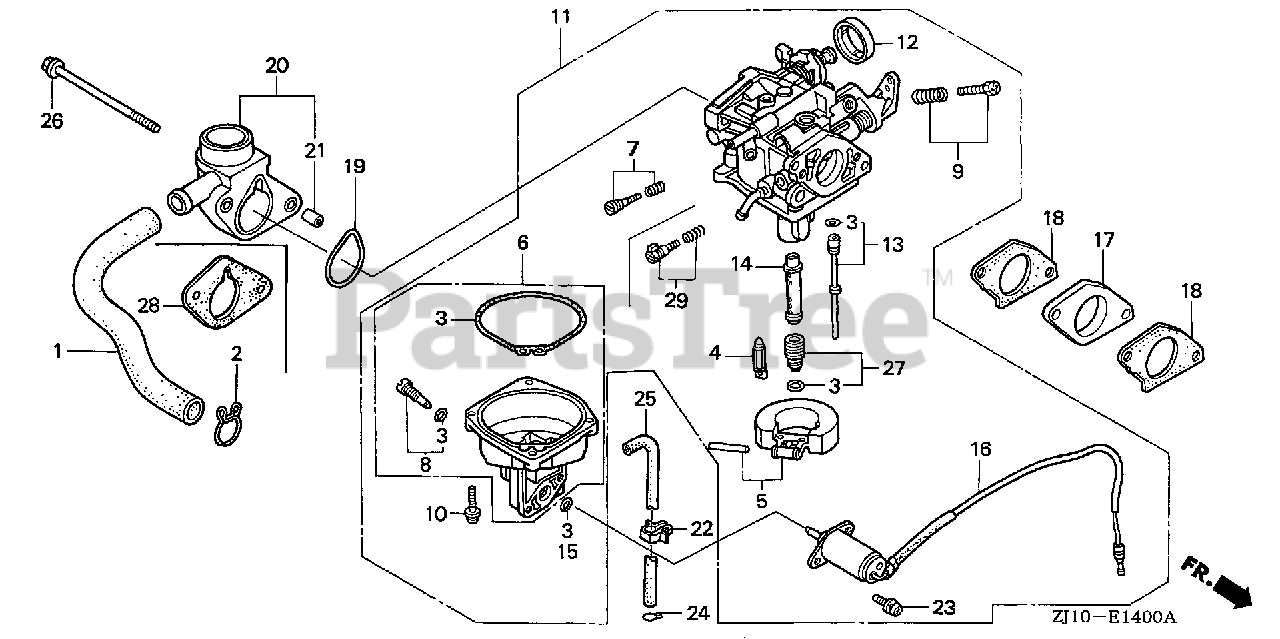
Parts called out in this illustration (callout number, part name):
1	TUBE, BREATHER
2	CLIP, BREATHER TUBE
3	GASKET SET
4	VALVE SET, FLOAT
6	CHAMBER SET, FLOAT
8	SCREW SET, DRAIN
9	SCREW SET (CARBURETOR NO.)
10	SCREW-WASHER
11	CARBURETOR ASSY. (BG22A C)
12	CAP, CHOKE DUST
13	JET SET (#45) (CARBURETOR NO.)
14	NOZZLE, MAIN
15	O-RING (5.8X1.9)
16	VALVE ASSY., SOLENOID
17	INSULATOR, CARBURETOR
18	GASKET, CARBURETOR
19	GASKET, AIR CLEANER
20	ELBOW, AIR CLEANER
21	COLLAR, DISTANCE
22	CLIP B, CABLE (9MM BLACK)
23	SCREW-WASHER (5X12)
24	CLIP, TUBE (B8)
25	BULK HOSE, VACUUM (4.5X1000) (4.5X460)
26	BOLT, FLANGE (6X105)
27	JET SET, MAIN (#90)
27	JET SET, MAIN (#92)
27	JET SET, MAIN (#95)
29	SCREW SET (CARBURETOR NO.)
